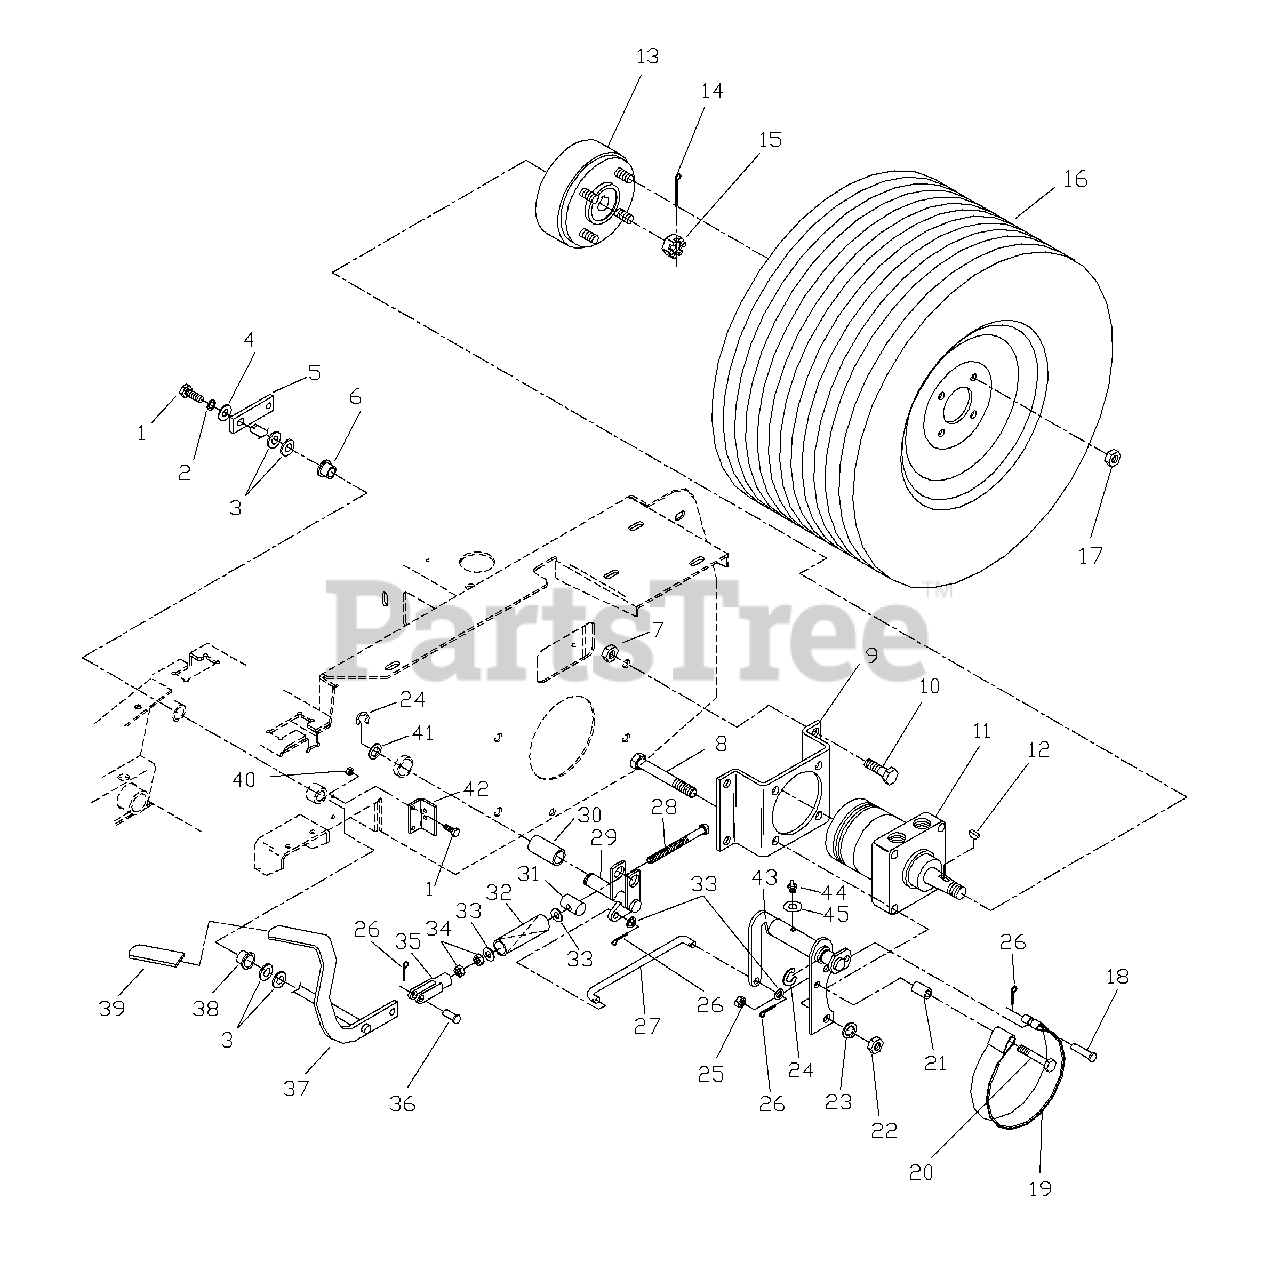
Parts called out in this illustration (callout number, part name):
1	HCS 1/4C X 3/4
2	1/4 LOCK WASHER
3	WASHER 7/16 SPRING
4	1/4 FLAT WASHER
5	ARM, PARK BRAKE
7	NUT 1/2C NYLOC
8	HCS 1/2C X 2.75
9	MOTOR STANDOFF
10	HCS 1/2C X 1.25
11	WHEEL MOTOR
12	WOODRUFF KEY
13	HUB W/ BRAKE DRUM
14	COTTER PIN
15	CASTLE NUT
16	REAR TIRE ASSEMBLY
17	LUG NUT 1/2F
18	3/8 X 1.50 CLEVIS PIN
19	BRAKE BAND
20	HCS 3/8C X 3 GD 8
23	1/2 LOCK WASHER
24	E - RING 3/4
25	NUT 3/8C CTR. LOCK
26	COTTER PIN
27	BRAKE LINKAGE LT.
27	BRAKE LINKAGE RT.
28	HCS 3/8F SPECIAL
30	BRONZE BEARING
31	TRUNION PIN
33	3/8 SAE WASHER
36	3/8 X 1.125
37	BRAKE LEVER WLDMT.
40	1/4C LOCK NUT
41	MACH. BUSHING 3/4
43	LEFT BRAKE BKT.
43	RIGHT BRAKE BKT.
44	ZERK
